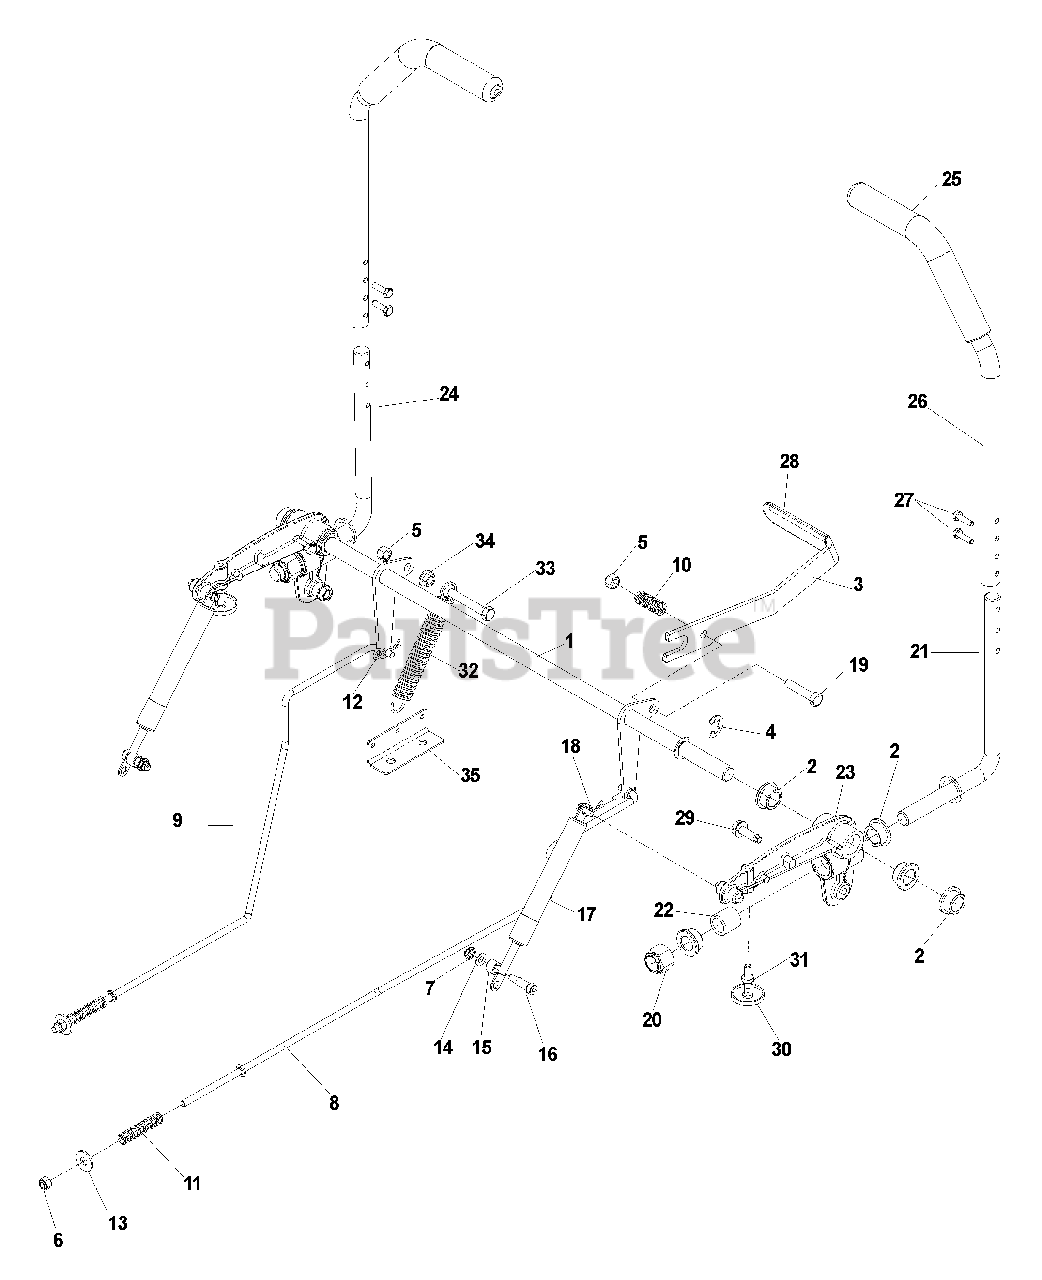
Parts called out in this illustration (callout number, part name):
1	SHAFT, MOTION, BRAKE ASS'Y
2	MOTION BUSHING
3	UPPER BRAKE LEVER
4	E-RING, 5/8
5	NUT, 5/16, NYLOC
6	NUT, 1/4C, NYLOC
7	NUT, 1/4C, THIN NYLOC
8	BRAKE ROD, RIGHT
9	BRAKE ROD, LEFT
10	SPRING, BRAKE LEVER
11	SPRING, ROD BRAKE
12	HAIRPIN COTTER
13	WASHER, 5/16
14	WASHER, 1/4
15	SPACER, PULLEY
16	BOLT, 5/16 X 5/8, SHOULDER
18	SCREW, 10-24 X 5/8, WASHER
19	HCS 5/16-18 X 1 1/2, GR5
20	NUT, 5/8-11C, NYLOC
21	MOTIONARM,
22	BUSHING, ELASTIMER
23	MOTION CASTING
24	MOTION ARM, LEFT
25	GRIP, CONTROL LEVER
26	CONTROL LEVER
27	HCS 1/4-20 X 7/8, GR5
28	GRIP, PARK BRAKE
29	BOLT, 5/16-18 X 1 1/4, THREAD FORM
30	POST, NEUTRAL RETURN
31	NUT, 1/4-20, JAM
33	HCS 5/16-18 X 2 GR5
34	NUT, 5/16-18 HFLN
35	SPRING BRACKET
